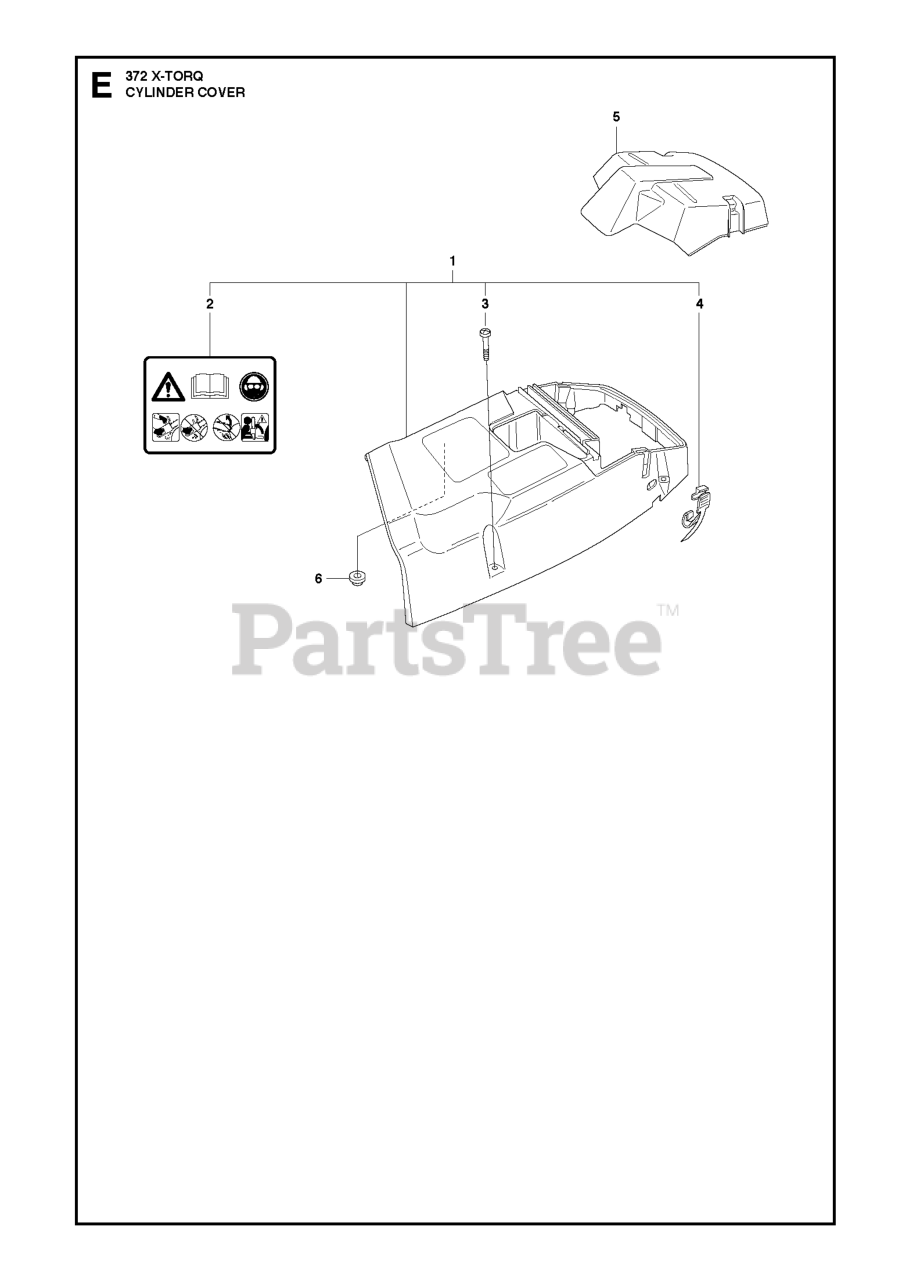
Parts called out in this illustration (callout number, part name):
1	RP CYLINDER COVER ASSY
3	SCREW
5	COVER
